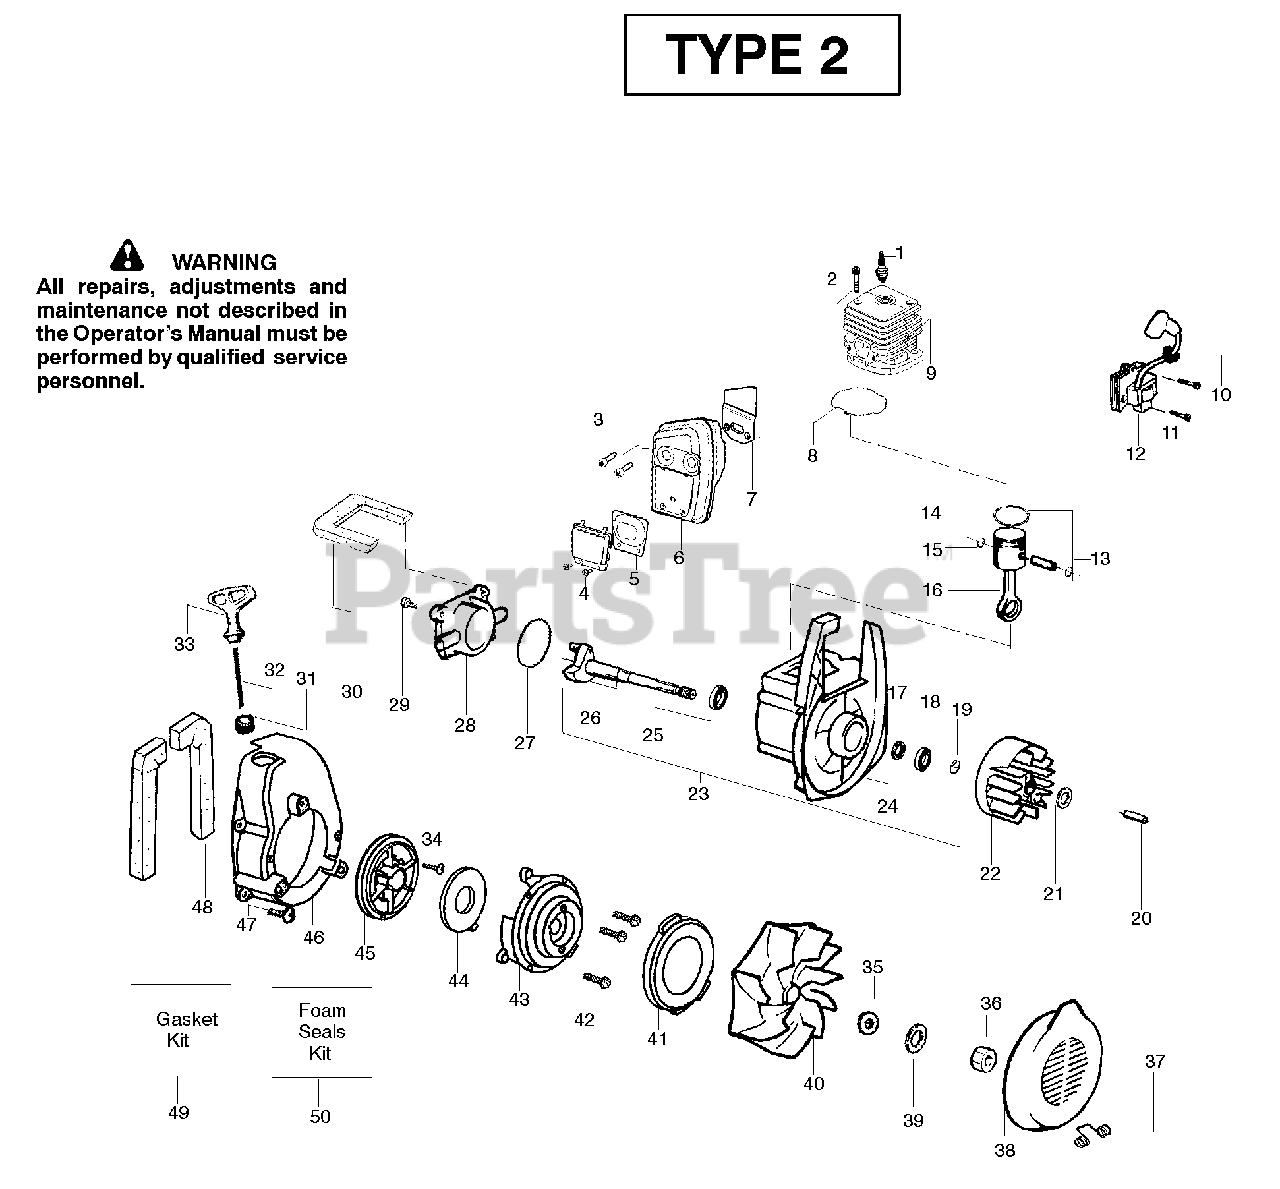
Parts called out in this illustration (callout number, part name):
1	Spark Plug (RCJ-6Y)
3	Screw-Muffler-Internal
5	Kit-Spark Screen
6	Kit-Muffler
7	Gasket-Baffle (kit)
8	Gasket-Cylinder (kit)
9	Kit-Cylinder
10	Grommet-Ign. Module
11	Screw-Ignition Module
12	Ignition Module
13	Kit-Piston
14	Piston Ring
15	Retainer-Piston Pin
16	Assy-Connecting Rod
17	Seal-Crankcase
18	Bearing-Outer
19	Retainer Ring-C'chaft
20	Spacer-Flywheel
22	Assy-Flywheel
23	Assy-Crankcase/Crank shaft
24	Assy-Crankcase
25	Bearing-Inner
26	Assy-Crankshaft
27	O-ring-C/case (kit)
28	Cover-Crankcase
29	Screw
30	Foam-219mm (kit)
31	Eyelet-Flange
32	Kit-Rope
33	Handle-Starter
34	Screw-Rope
35	Washer-Belleville
37	Spring-Return Cover
38	Inlet Door
40	Assy-Impeller
41	Seal-Ring
43	Housing-Pulley
44	Spring-Starter
45	Kit-Starter Pulley
46	Fan Housing
47	Screw
48	Foam-182mm (kit)
49	Kit-Gasket
50	Kit-Foam Seals
